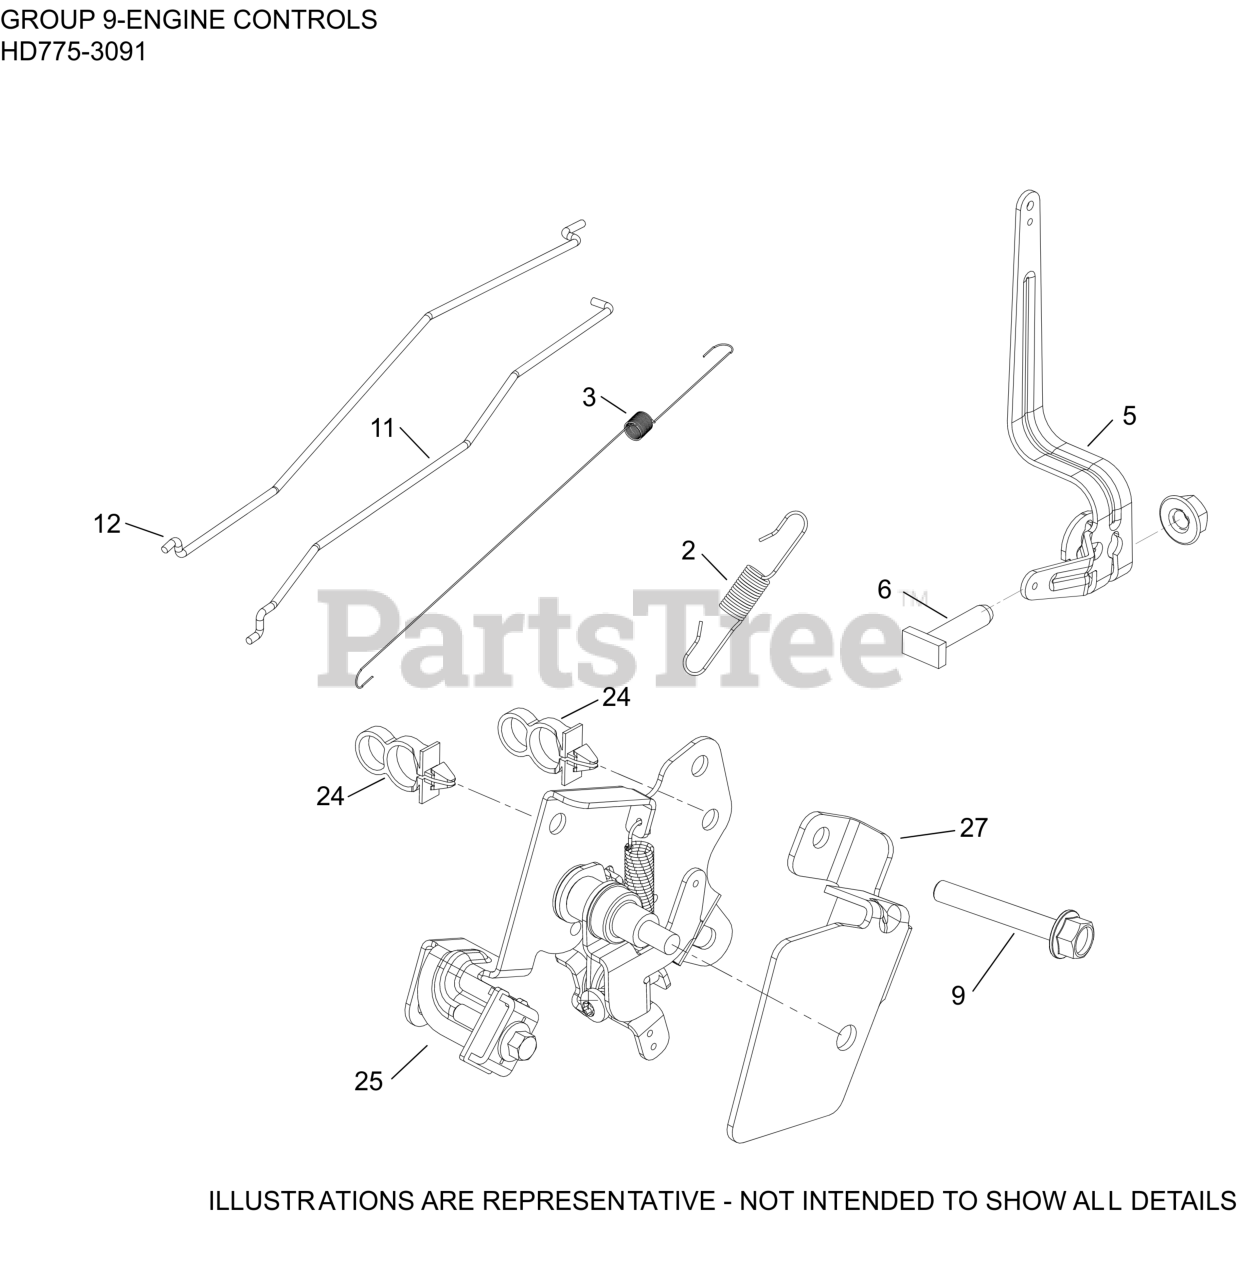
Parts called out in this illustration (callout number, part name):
2	SPRING, GOV (2800-3300 RPM)
3	SPRING, LINKAGE
5	LEVER, GOVERNOR
6	SCREW, RECTANGLE HEAD (M6)
9	SCREW, HEX FLANGE (M6)
11	LINKAGE, GOVERNOR
12	LINKAGE, CHOKE
24	CLIP, FUEL LINE
25	CONTROL ASSY, VARIABLE SPEED NO-KILL
27	GUARD, SPEED CONTROL ASSEMBLY
